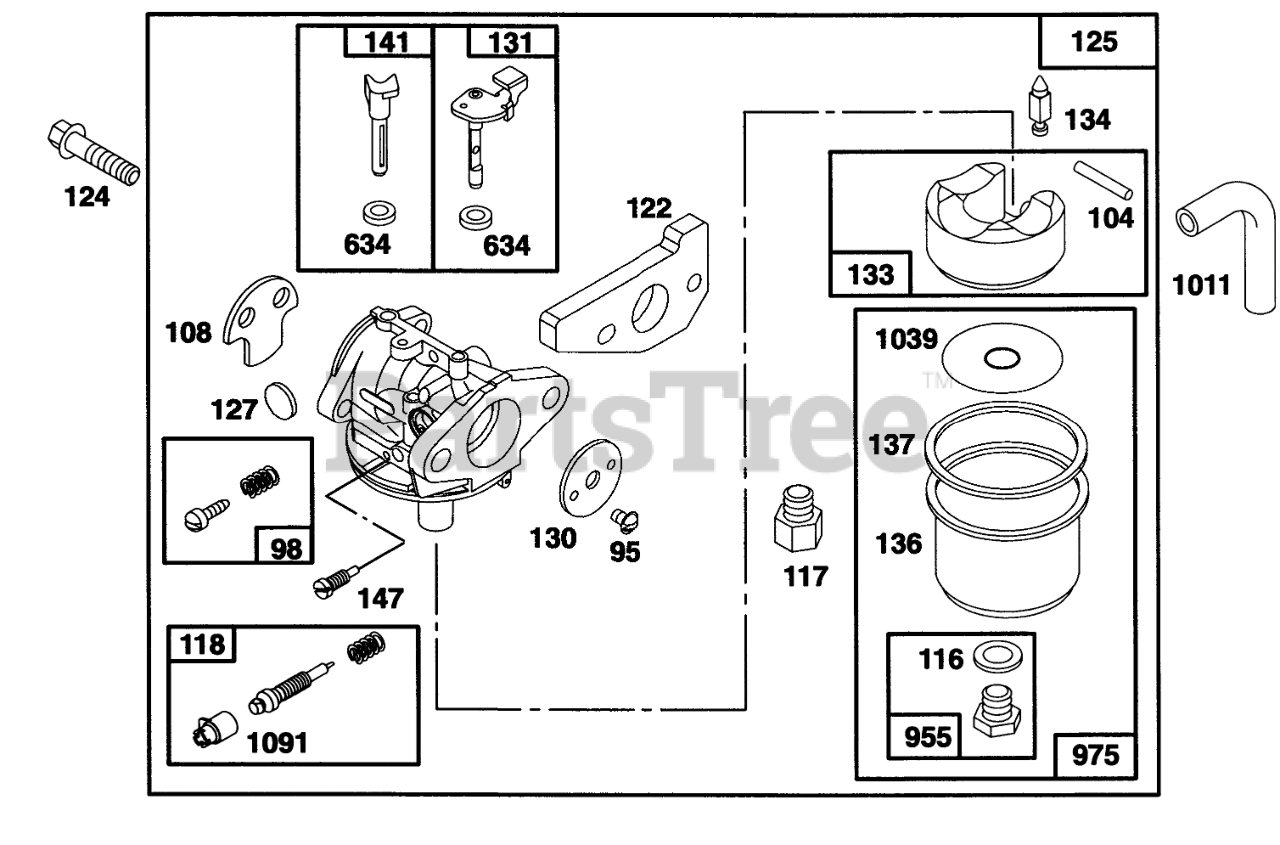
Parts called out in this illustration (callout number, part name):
37	GUARD - FLYWHEEL
95	SCREW - ROUND HEAD
98	IDLE ADJUSTING SCREW
104	FLOAT HINGE PIN
108	VALVE - CHOKE
116	SEALING GASKET
117	Jet-Main
118	VALVE/SPRING - NEEDLE
122	ADAPTER ASSEMBLY
124	HEX HEAD SCREW
125	ASSEMBLY - CARBURETOR
127	PLUG - WELCH
130	THROTTLE VALVE
131	THROTTLE SHAFT
133	FLOAT-CARBURETOR
134	Valve-Inlet (Includes Seat)
136	FLOAT BOWL
137	FLOAT BOWL GASKET
141	CHOKE SHAFT
147	JET - PILOT
634	SEAL WASHER
955	HEX HEAD SCREW
975	CARBURETOR BOWL ASM
1011	VENT TUBE
1039	FLOAT LIMITER
1091	CAP - LIMITER
